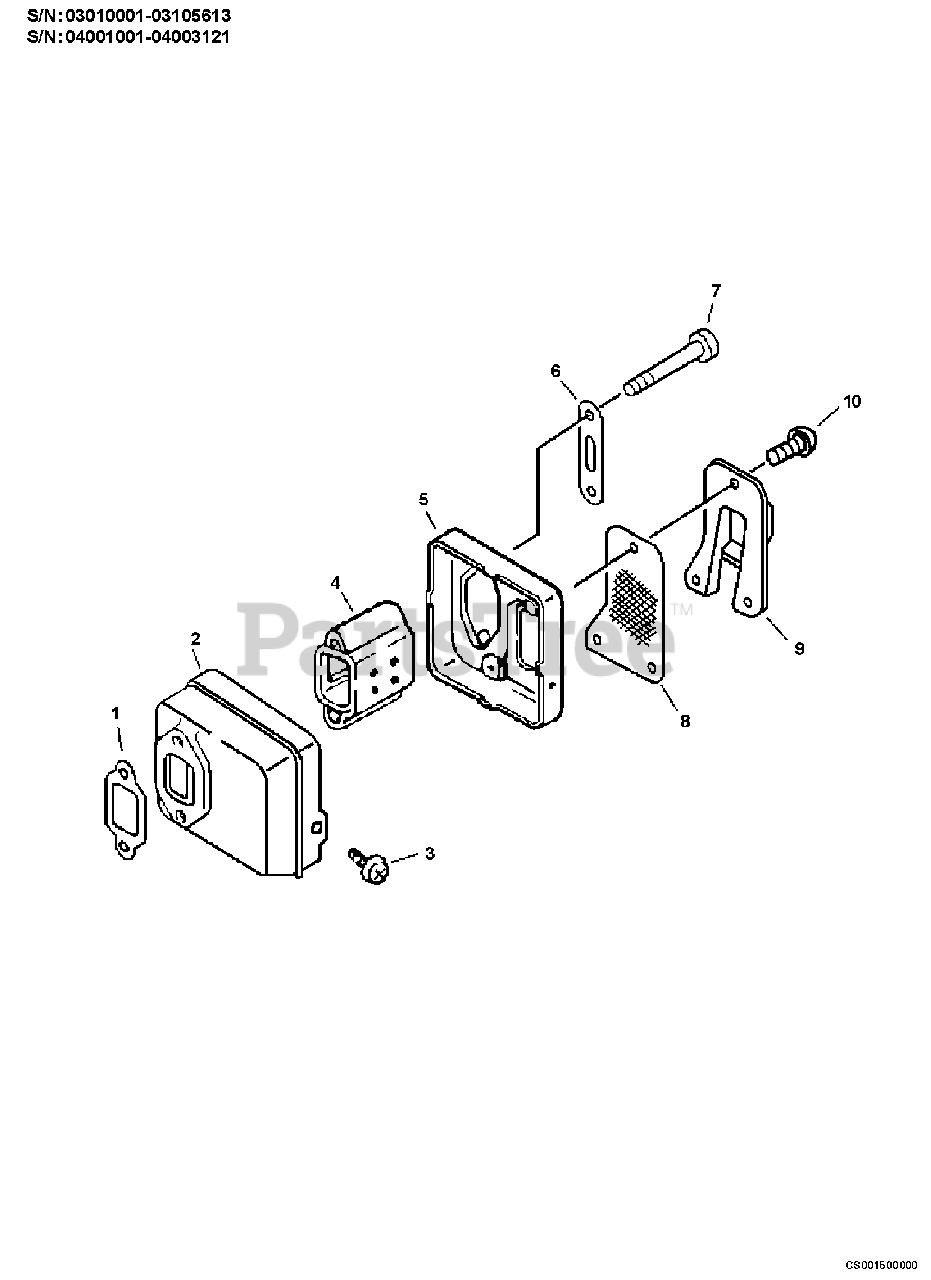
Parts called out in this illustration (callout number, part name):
1	GASKET, EXHAUST
2	GUIDE, EXHAUST
3	SCREW - 4X8
4	BAFFLE, MUFFLER
5	GUIDE, EXHAUST
7	BOLT - FLANGE
8	SCREEN, SPARK ARRESTOR
9	GUIDE, EXHAUST
10	SCREW - 4X8
